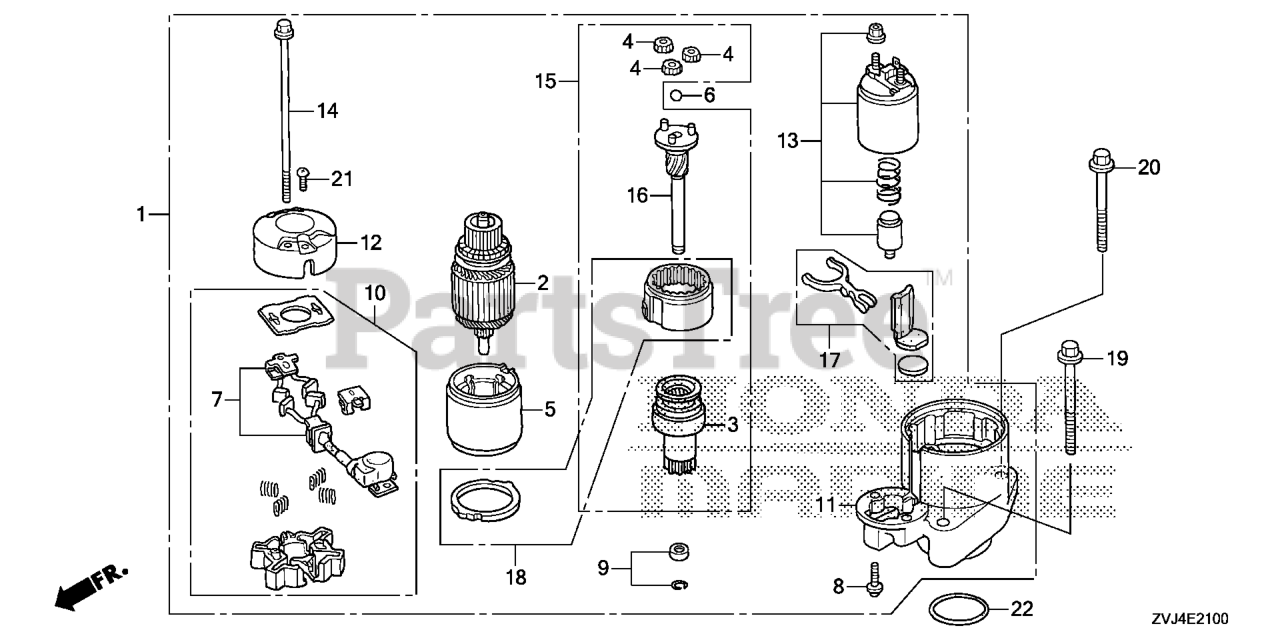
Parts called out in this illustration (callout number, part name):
1	STARTER MOTOR ASSY.
3	CLUTCH, OVERRUNNING
4	GEAR ASSY., PLANETARY
6	BALL, STEEL
8	SCREW, PAN (6X22)
9	STOPPER SET, SLEEVE
10	HOLDER, BRUSH
11	BRACKET, FR.
12	BRACKET, RR.
13	SWITCH ASSY., MAGNET
14	BOLT A, THROUGH
15	SHAFT ASSY., CLUTCH
16	SHAFT ASSY., GEAR
18	GEAR ASSY. (INNER)
19	BOLT, FLANGE (10X110)
19	BOLT, FLG (10X110)
20	BOLT, FLANGE (10X90)
21	SCREW, PAN (5X8)
22	O-RING (59.4X3.1)
